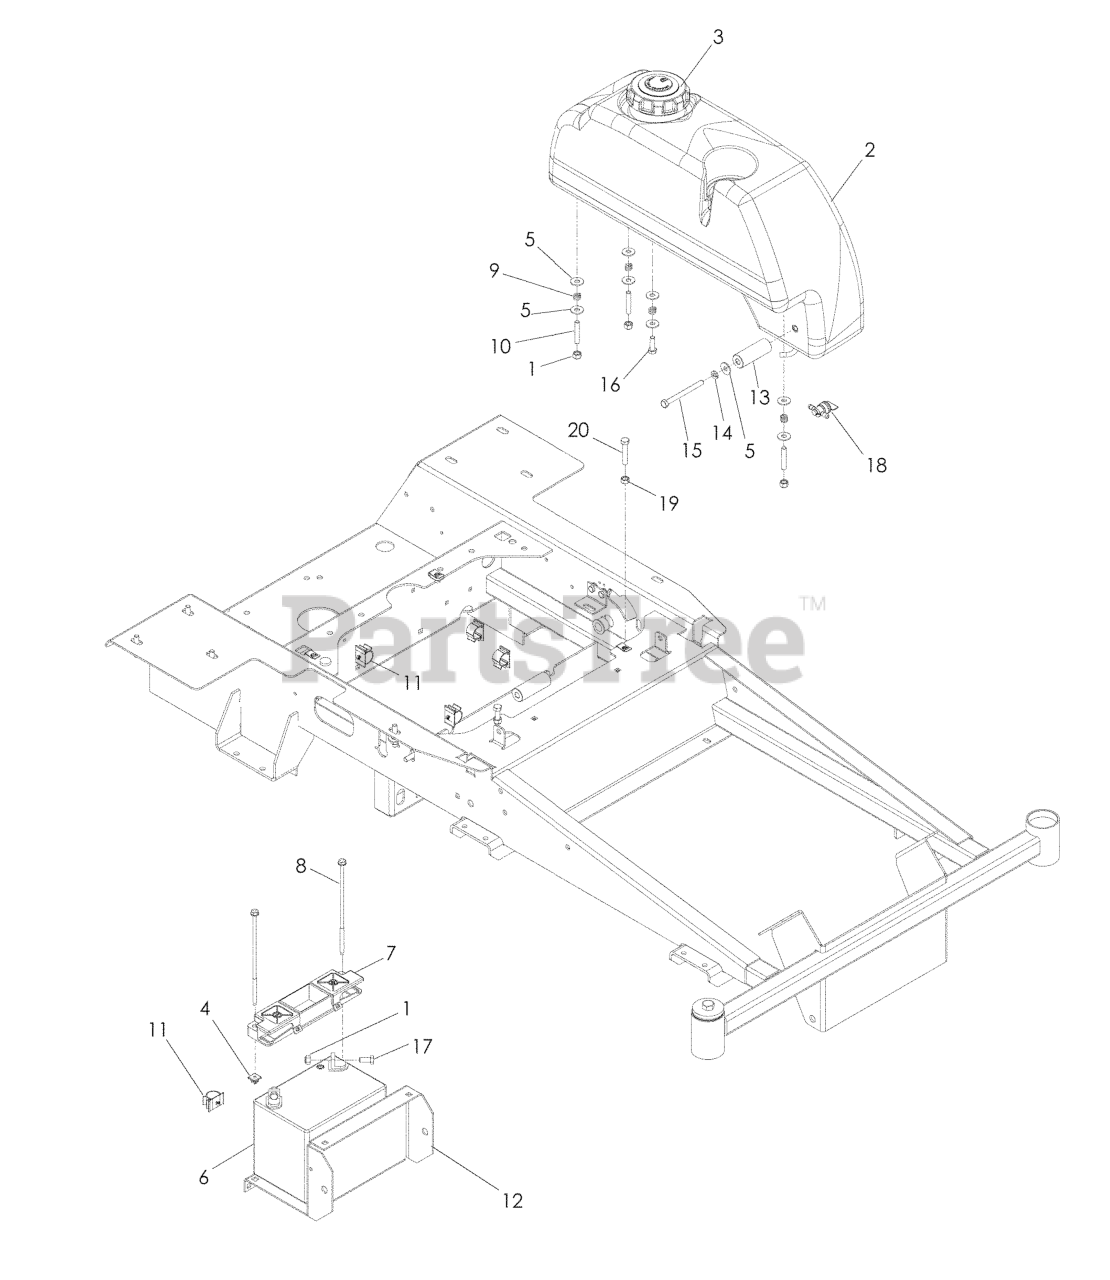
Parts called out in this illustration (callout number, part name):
1	NUT 5/16 NYLOC
2	LEFT TANK W/CUP HOLDER
3	FUEL CAP ANTI-SPLASH
4	PUSH NUT-NYLON
5	WASHER 5/16 FLAT
6	BATTERY, 12 V 330 AMP
7	BATTERY HOLD DOWN
8	BOLT - 1/4-20 X 7.5
10	STUD, 5/16C
11	PUSH-MOUNT WIRE CLIP
12	BATTERY TRAY
13	TANK SPACER
14	WASHER.LOCK.HVY.HLCL.SPR.5/16
15	BOLT - HCS 5/16C X 3.5
16	HCS 5/16C X 1
17	HCS 5/16C X 3/4
18	FUEL VALVE
19	NUT 5/16C HEX
20	HCS 5/16-18X1-3/4 TPBLT
